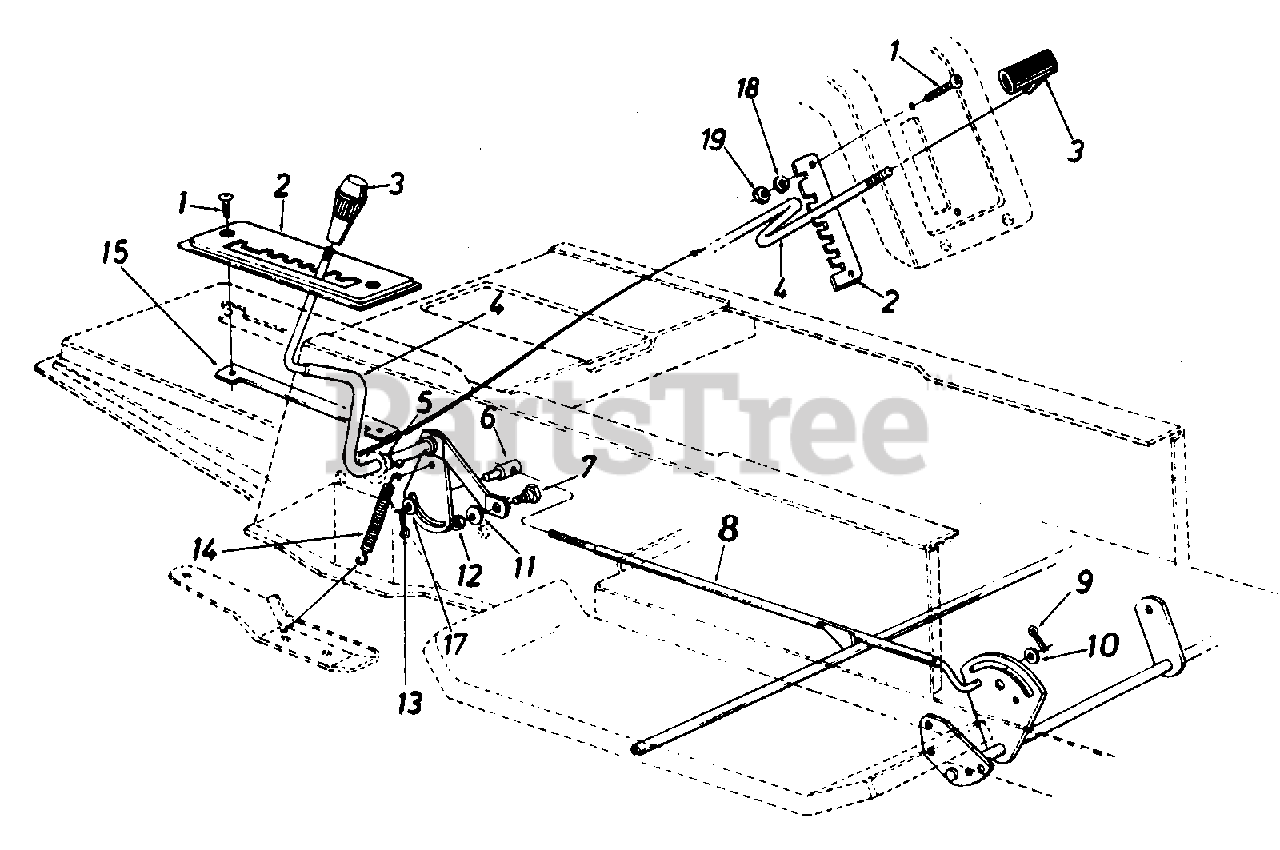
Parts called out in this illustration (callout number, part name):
1	Truss Mach. Scr. 1/4-20 x .75" Lg.
3	Shift Knob
4	Speed Selector Cam Ass'y.
5	Flat Washer .53" I.D. x .93"
6	Ferrule 3/8-24 x .37" Dia.
7	Shoulder Bolt .435" Dia. x .160
8	Speed Control Rod Ass'y.
9	Cotter Pin 3132" Dia. x .75"
10	Fl-Wash. .469" I.D. x .88"
11	L-Wash. 5/16" I.D.
12	Hex Nut 5/16-18 Thd.
13	Cotter Pin 3132" Dia. x .751"
14	Spring .38" O.D. x 3.18" Lg.
15	Clamping Plate
17	Fl-Wash. .385" I.D. x .62"
18	L-Wash. 1/4" I.D.*
19	Hex Nut 1/4-20 Thd.*
